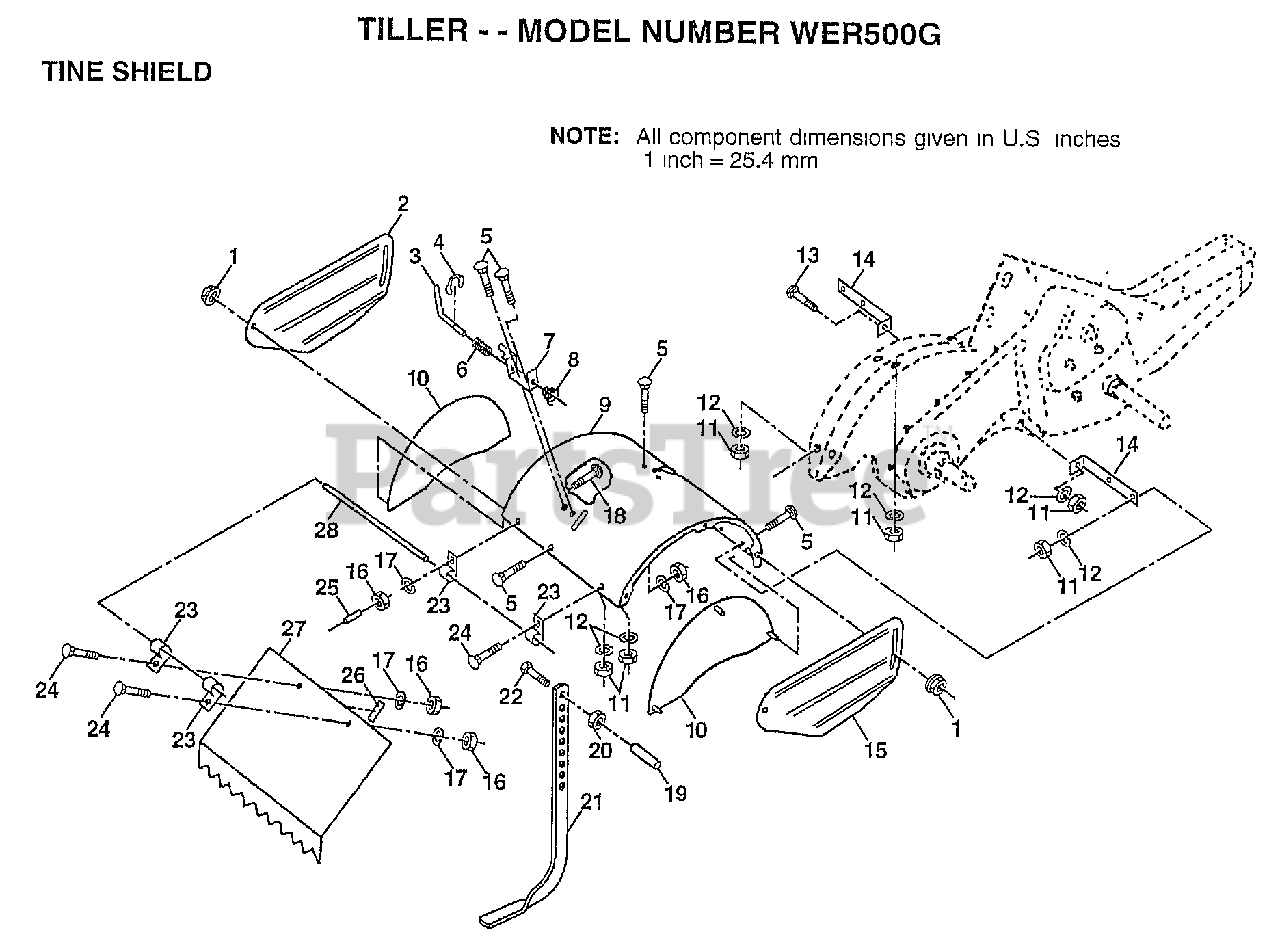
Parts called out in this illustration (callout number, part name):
1	NUT
2	SHIELD.OUT.SD.LH.
3	STAKE PIN TI
4	KLIP RING TI
5	BOLT
6	SPRING TI
7	LATCH BRACKET TI
8	SPRING CRT
9	SHIELD.TINE.PNT.
10	SHIELD.SD.INNER
11	NUT.HEX.5/16-18
12	LOCKWASHER
13	BOLT
14	BRKT SHIELD TINE
15	SHIELD.OUT.SD.RH.
17	LOCKWASHER
18	BOLT
19	GRIP CRT
20	NUT.HEX.3/8-16UNC
22	BOLT
23	HINGE CRT
24	BOLT
25	VINYL CAP TI
26	PAD IDLER TI
27	SHIELD.LEVELING
28	PIN HINGE
